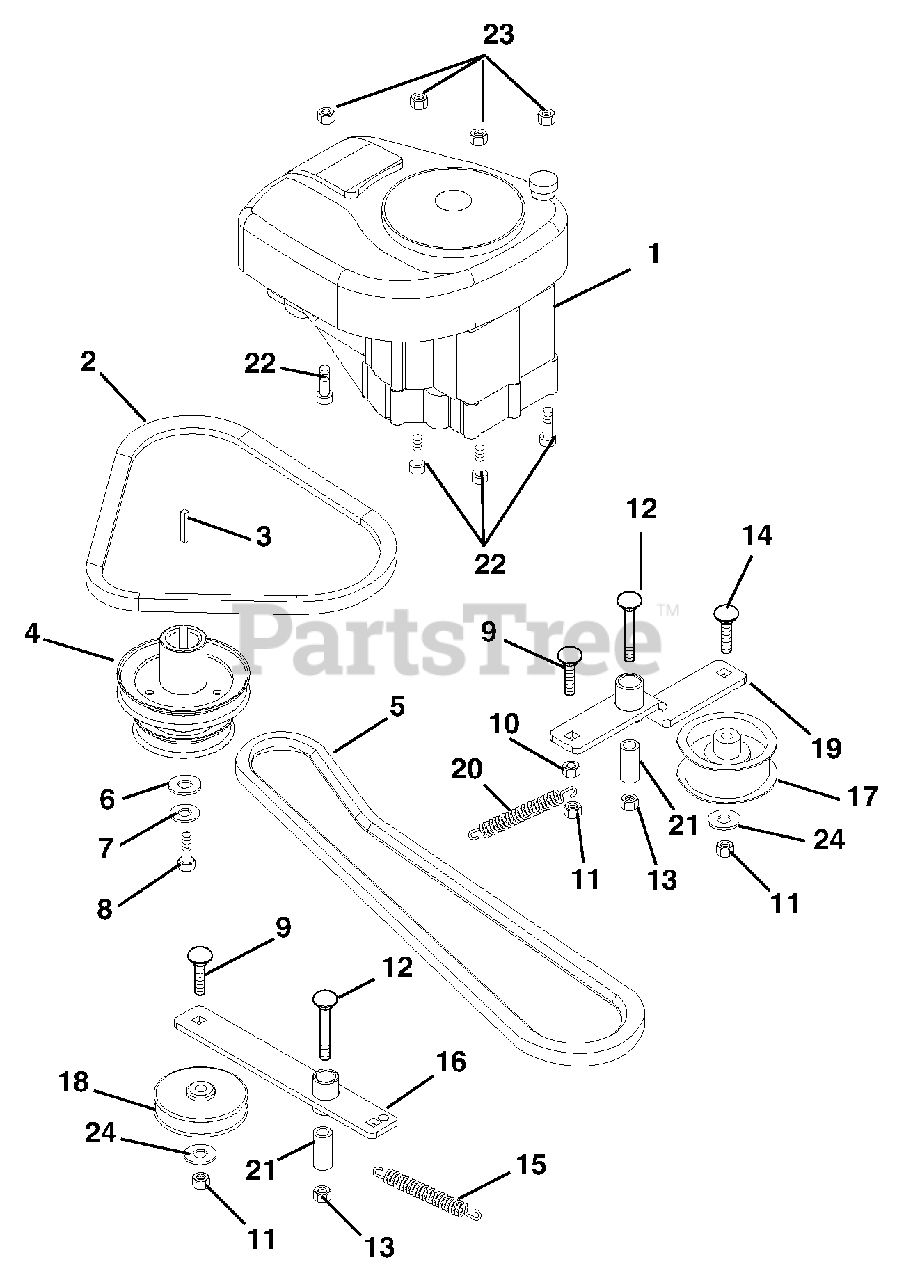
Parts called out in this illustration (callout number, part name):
1	Group, Engine 12HP Intek (062)
1	Group, Engine 10HP Intek (060)
1	Group, Engine 14HP Intek (064)
2	V-Belt 4L-Section 30.219 x .547
3	Key, Straight .25 x 1.75 x .25
4	Stack, Sheave (060, 062)
4	Stack, Sheave (064)
5	Belt, PTO (062)
5	Belt, PTO (060)
5	Belt, PTO (064)
6	Washer, Flat Steel .463 x 1.375 x .25
7	Washer, Locking .44 x .109 Regular
8	Bolt, Hex .44-20 x 1.75 Grade 5
9	Bolt-Round Head Square Neck .38-16 x 1.50 Grade 5
10	Nut-Flange .375-16
11	Nut, Locking Top Flange .38-16
12	Bolt, Round Head Square Neck .50-13 x 2.75
13	Nut, Locking Top Flange .50-13
14	Bolt-Round Head Square Neck .38-16 x 2.00 Grade 5
15	Spring, Tension .095 x .50 x 5.50
16	Idler, Drive
17	Sheave 3.25 x 1.25
18	Idler, V 3 x .38
19	Idler, 32" Deck PTO (060, 062)
19	Idler, 40" Deck PTO (064)
20	Spring, Extension.093 x .75 x 4.00
21	Bushing-Sleeve .50 x .75 x 1.56
22	Screw, Socket Head Button Head .31-18 x 1.50 Grade 8
23	Nut-Locking-Top-Flange .31-18
24	Washer-Flat-Steel .38 x .875 x .083
